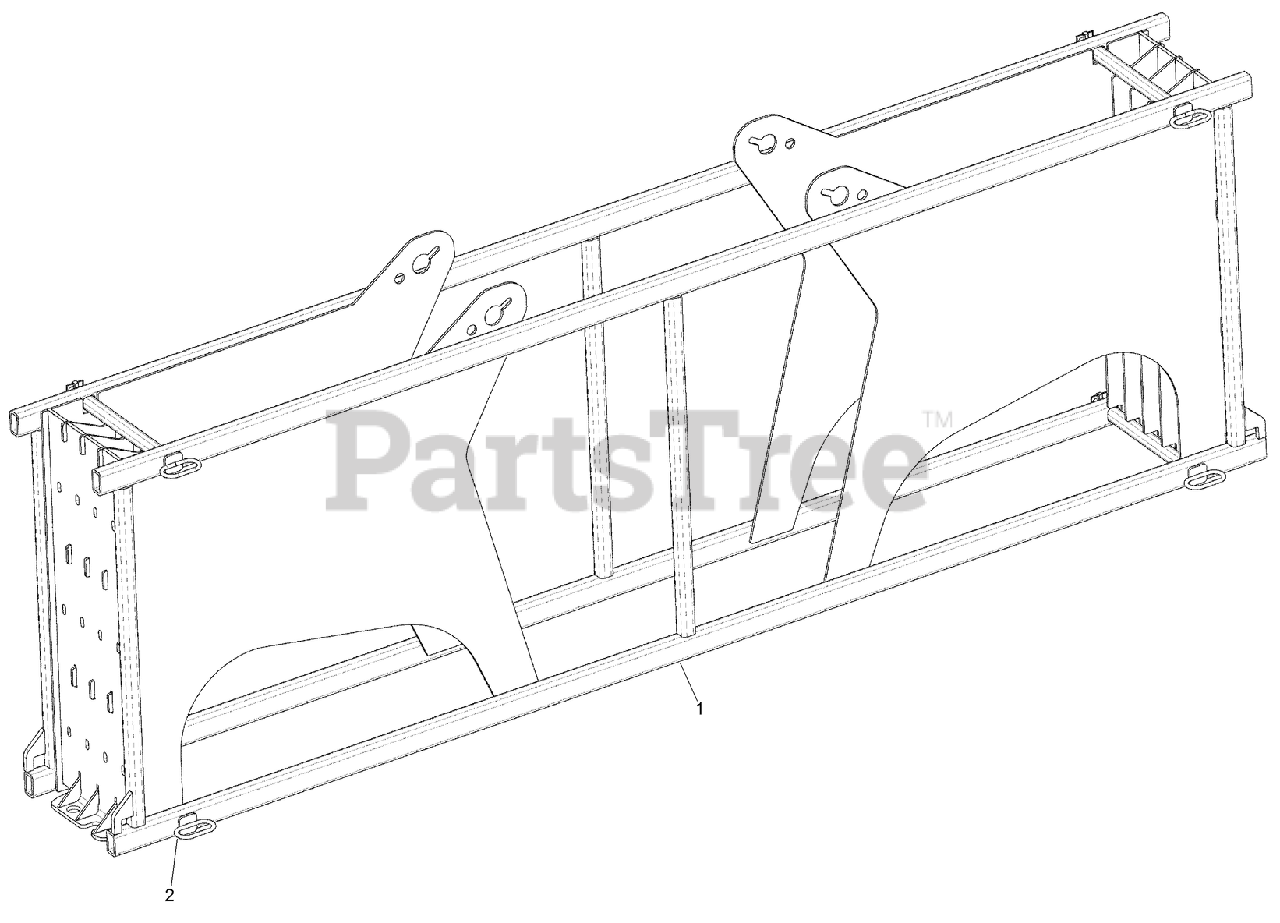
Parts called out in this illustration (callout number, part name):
1	WELDMENT - TJOD Rod Box, 2.80
2	ASSEMBLY - Rod Box Pin
3	COVER - Pipe Basket
